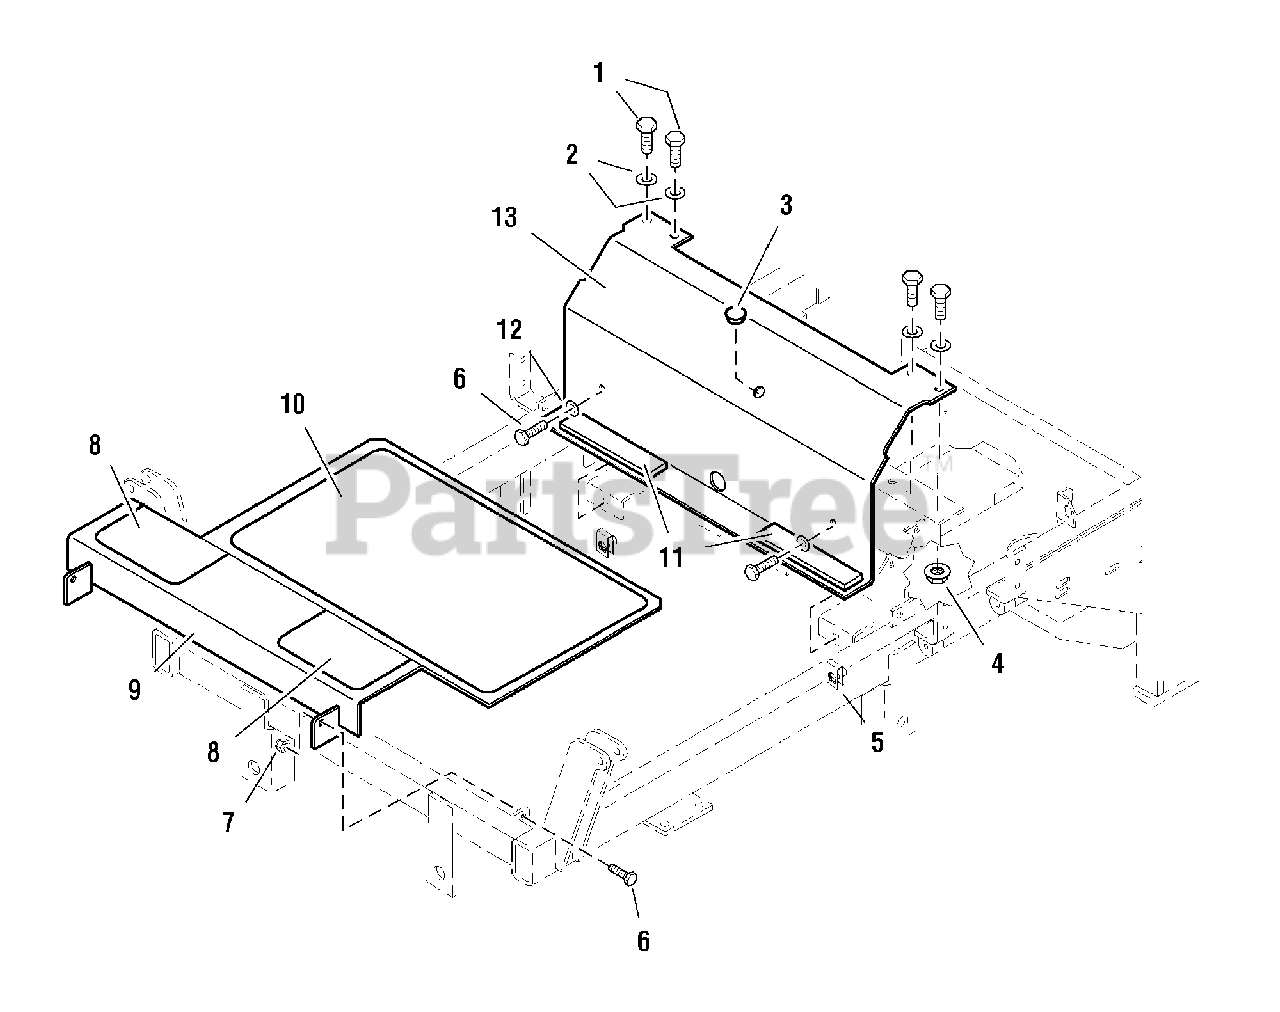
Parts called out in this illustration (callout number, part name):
1	CAPSCREW, Hex Hd, 3/8-16 x 1
2	WASHER, 3/8
4	NUT, Hex, Serrated Flange, 3/8-16
5	BODY CLIP, 5/16-18
6	CAPSCREW, Hex Hd, 5/16-18 x 3/4
7	NUT, Hex, Nylon Lock, 5/16-18
8	SAFETY WALK
10	SAFETY WALK
12	WASHER, 5/16
13	BRAKE COVER PANEL
